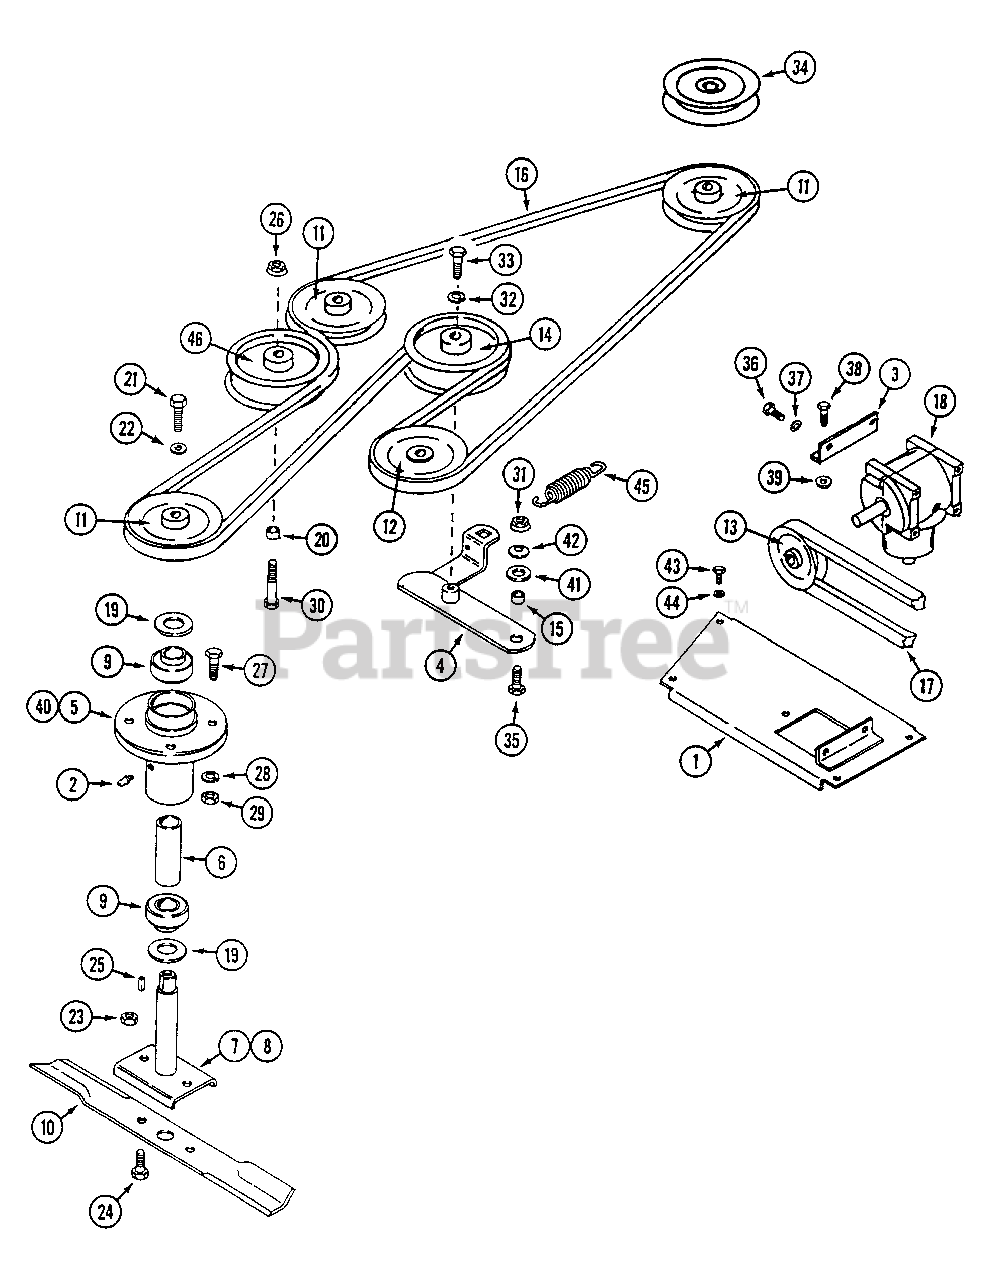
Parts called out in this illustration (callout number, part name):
1	MOUNT - gear box
2	FITTING - grease 1/4" - 28
3	ANGLE - gear box mount
4	ARM - idler
5	HOUSING - spindle
6	SPACER - spindle
7	SHAFT - spindle, short
8	SHAFT - spindle, long
9	BEARING - spindle
11	PULLEY - spindle
12	PULLEY - gear box output
13	PULLEY - gear box input
14	PULLEY - idler 5"
18	GEAR BOX - angle drive
19	WASHER - spacer
21	BOLT - 3/8" - 24 x 1-1/4"
22	WASHER - 3/8", 10 ga.
23	NUT - lock 3/8"
24	BOLT - 3/8" - 16 x 1"
25	KEY - 3/16" x 3/16" x 1"
26	NUT - 3/8" flange lock
27	BOLT - 7/16" - 14 X 1-1/4"
28	LOCKWASHER - 7/16"
29	NUT - 7/16" - 14
30	BOLT - 3/8" - 16 x 2-1/4"
31	NUT - 3/8" flange lock
32	LOCKWASHER - 3/8"
33	BOLT - 3/8" - 16 x 1-1/4"
34	PULLEY - vac drive
35	BOLT - 3/8" - 16 x 1"
36	BOLT - 5/16" - 18 x 1"
37	LOCKWASHER - 5/16"
38	BOLT - 5/16" - 18 x 3/4"
39	NUT - 5/16" - 18 flange lock
40	HOUSING ASSEMBLY - spindle
41	WASHER - 5/8"
42	WASHER - spring
43	BOLT - 1/4" - 20 x 3/4"
44	LOCKWASHER - 1/4"
45	SPRING - tension
46	PULLEY - idler, idler 5-1/2"
